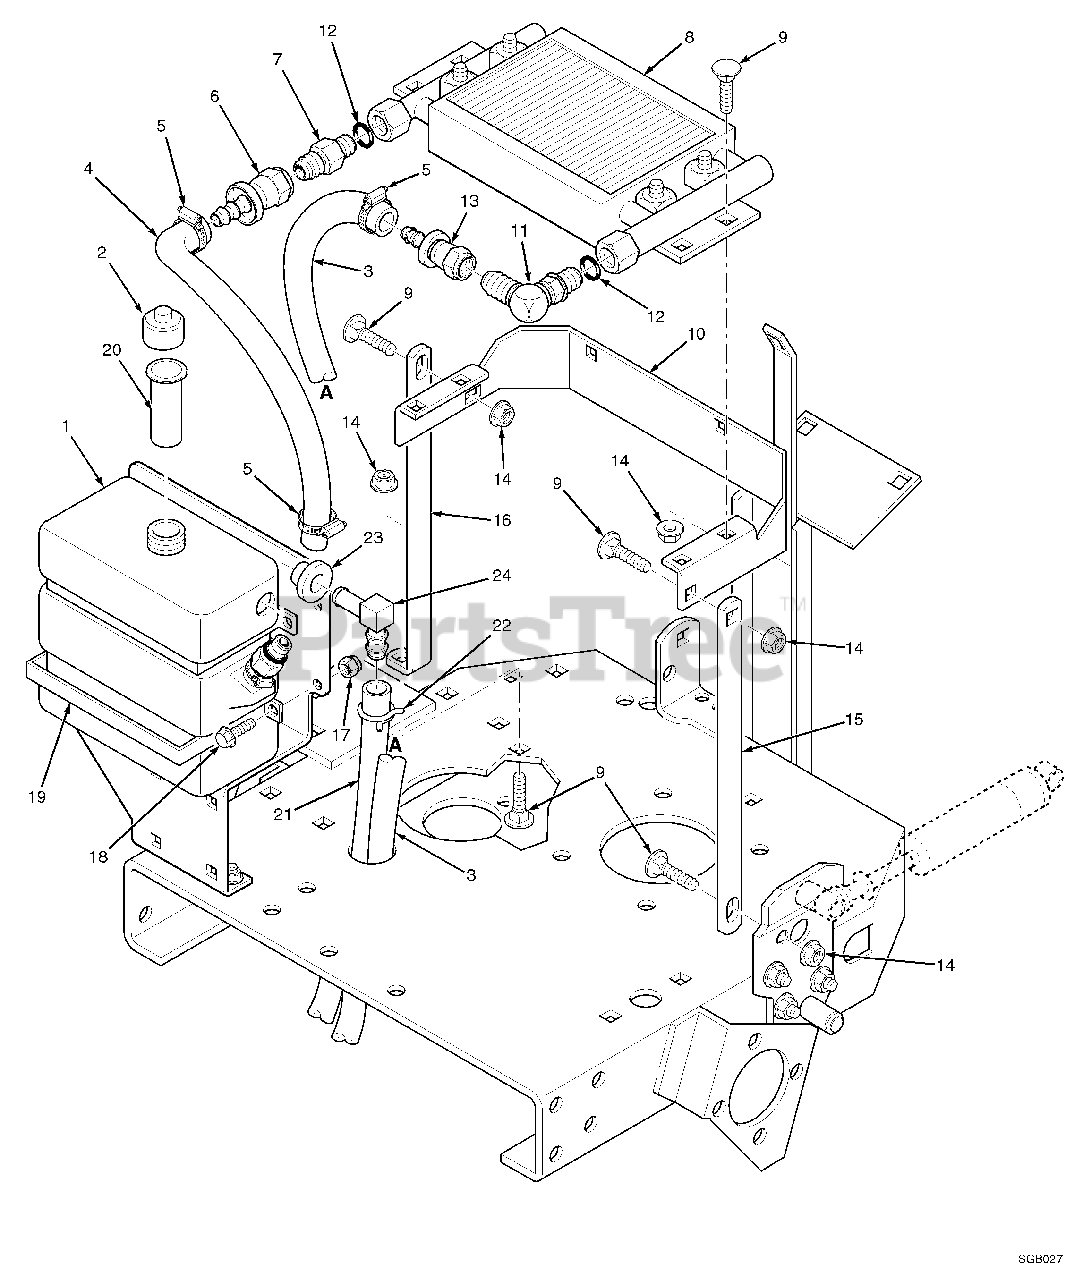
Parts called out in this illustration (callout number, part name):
1	Tank, Hydraulic
2	Cap, Hydraulic Tank
3	Hose, Pump to Oil Cooler
4	Hose, Oil Cooler to Tank
5	Clamp, Hose
6	Coupling, Flare Swivel
7	Tube, Union
8	Oil Cooler Assembly
9	Carriage Bolt, 5/16-18 x 3/4"
10	Bracket, Oil Cooler
11	Elbow, 90 Degrees
12	O-Ring
13	Coupling Flare Swivel
14	Serr. Fl. Hex Head Nut, 5/16-18
15	Brace, L.H. Cooler Support
16	Brace, R.H. Cooler Support
17	Elastic Stop Nut, 1/4-20
18	Serr. Fl. Hex Head CPSCR, 1/4-20 x 3/4"
19	Strap, Oil Tank
20	Filler Neck Insert
21	Hose, 1/4" Pushlock
23	Bushing
24	90 Degree Elbow
